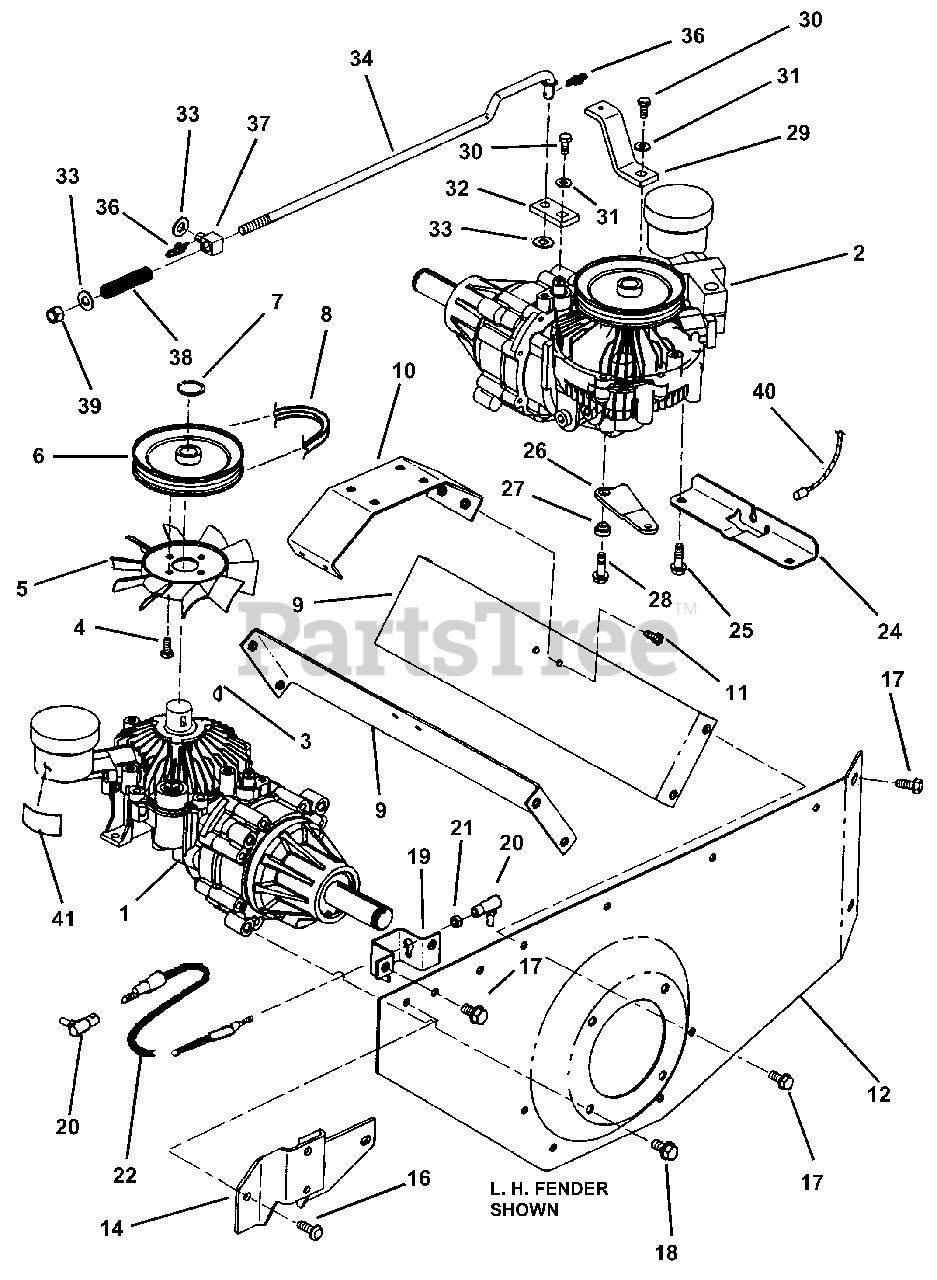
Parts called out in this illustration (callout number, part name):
1	TRANSAXLE, Hydro L.H.
2	TRANSAXLE, Hydro w/o Manifold R.H.
3	KEY, #605 Woodruff
4	SCREW, 1/4-20 x 1/2" Self-Tapping
5	FAN, 6" O.D., 10 Blade
6	PULLEY, Hydro Input
7	RING, Retaining
8	V-BELT, Hydro Drive
9	BRACKET, Fender Support
10	BRACKET, Hydro Support
11	SCREW, 1/4-20 Hex Washer Head, Self-Tapping
12	FENDER, L.H,
14	BRACKET, Deck Support L.H.
16	SCREW, 5/16-18 x 7/8" Pan Head, Self-Tapping
17	SCREW, 5/16-18 x 3/4" Hex Washer Head, Self-Tapping
18	SCREW, 3/8-16 x 3/4" Hex Washer Head, Self-Tapping
19	BRACKET, Hydro Control Cable
20	ROD END, #10-32 w/Stud
21	NUT, #10-32 Hex Center Lock
22	CABLE, L.H. Hydraulic Control (45.5" long)
24	BRACKET, Hydro Release Cable
25	SCREW, 5/16-18 x 5/8" Hex Washer Head, Self-Tapping
26	BRACKET, Hydro Release Actuator
27	BUSHING,
28	SCREW, 5/16-18 x 1" Hex Washer Head, Self-Tapping
29	ARM, Brake
30	BOLT, 1/4-28 x 5/8" Hex Head, Grade 8
31	WASHER, 1/4 Belleville
32	ARM, Brake
33	WASHER, 3/8" Flat
34	ROD, R.H. Brake
36	COTTER-PIN, 1/16" x 1.42" Self-Locking
37	LINK, Swivel Brake
38	SPRING, Brake Compression
39	NUT, 3/8-16 Nyloc
40	CABLE, Hydro Release Valve
41	DECAL, Hydro Reservoir
